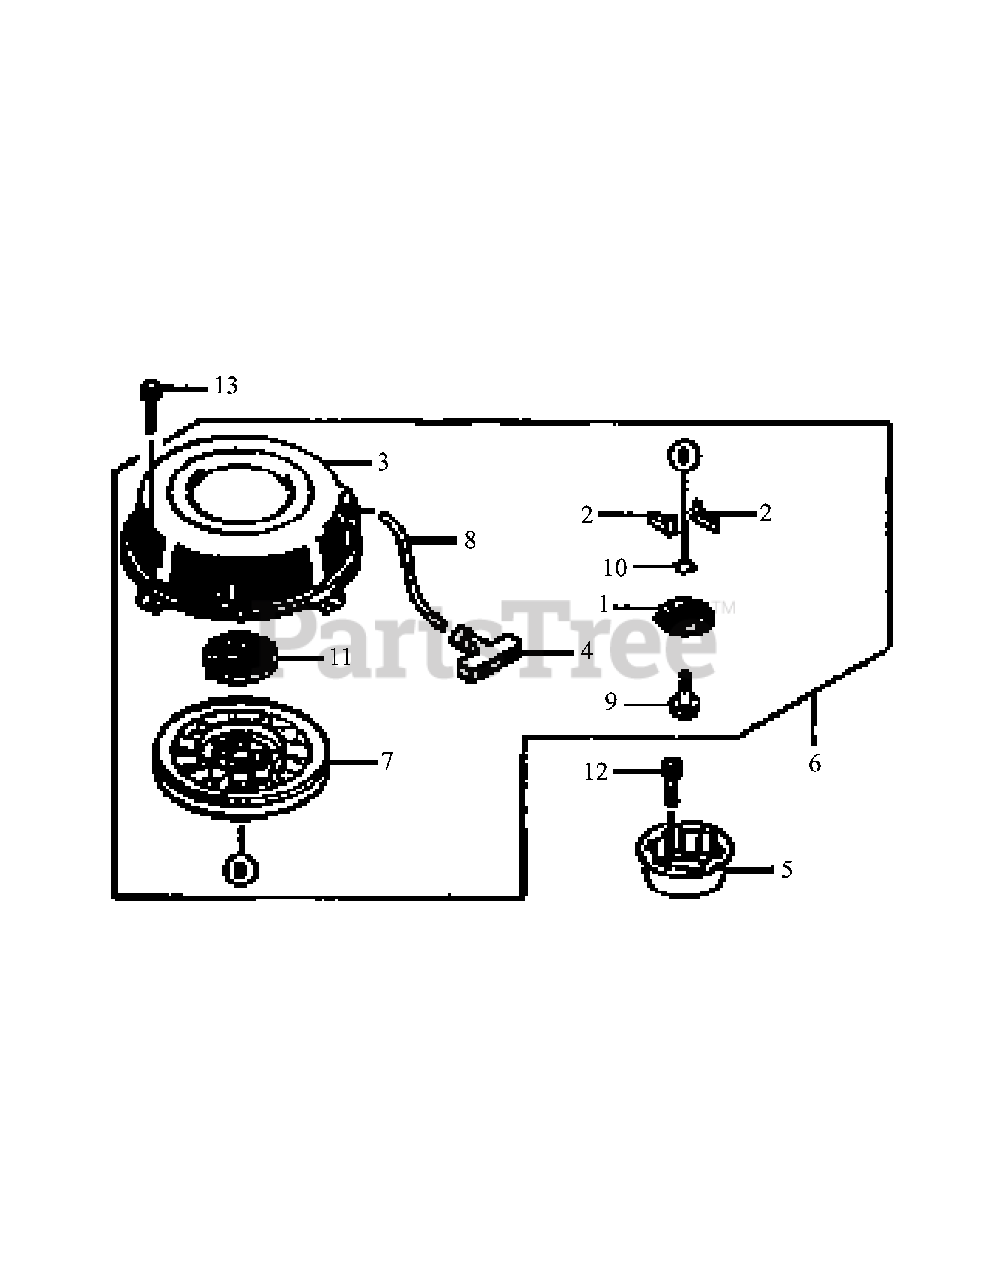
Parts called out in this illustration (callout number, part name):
2	Pawl, Recoil Starter
3	Case, Recoil Starter
4	Grip, Recoil Starter
5	Pulley, Starting
6	Starter, Recoil
7	Reel, Recoil Starter
11	Spring
12	Bolt, Socket
13	Bolt, Flange
